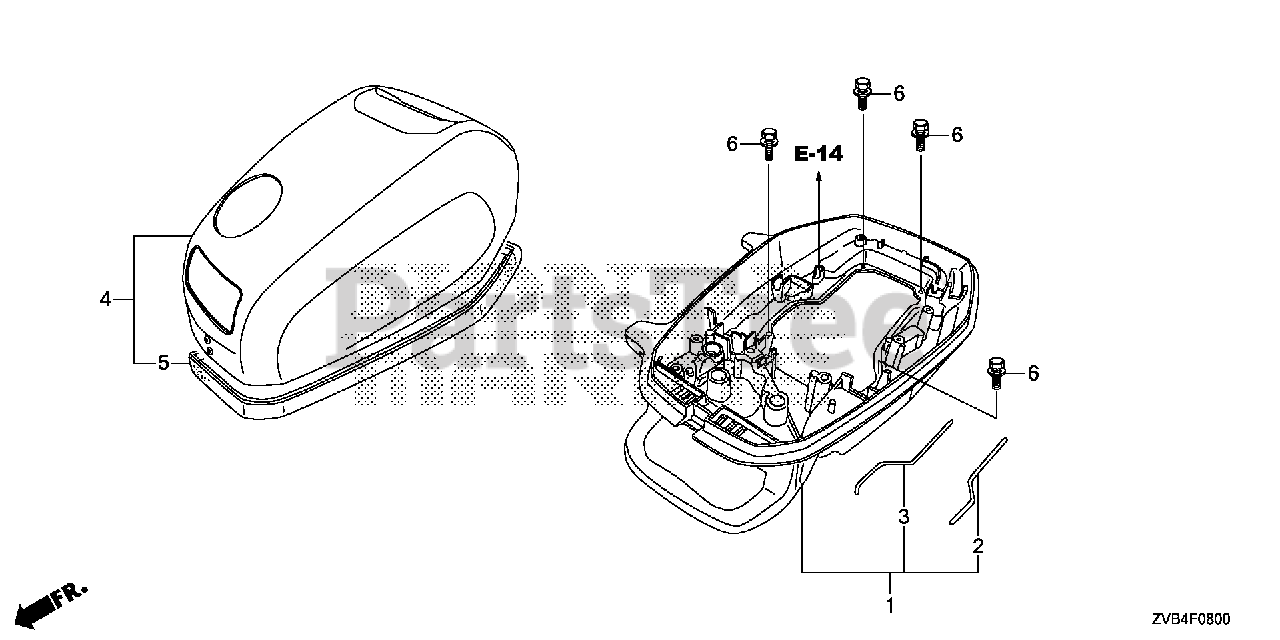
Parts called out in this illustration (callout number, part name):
1	CASE, ENGINE (LOWER) *NHB14M* (AQUA MARINE SILVER METALLIC)
2	SEAL A, CASE (LOWER)
3	SEAL C, CASE (LOWER)
4	COVER, ENGINE *NHB14M* (AQUA MARINE SILVER METALLIC)
5	SEAL, ENGINE COVER
6	BOLT-WASHER (6X16)
